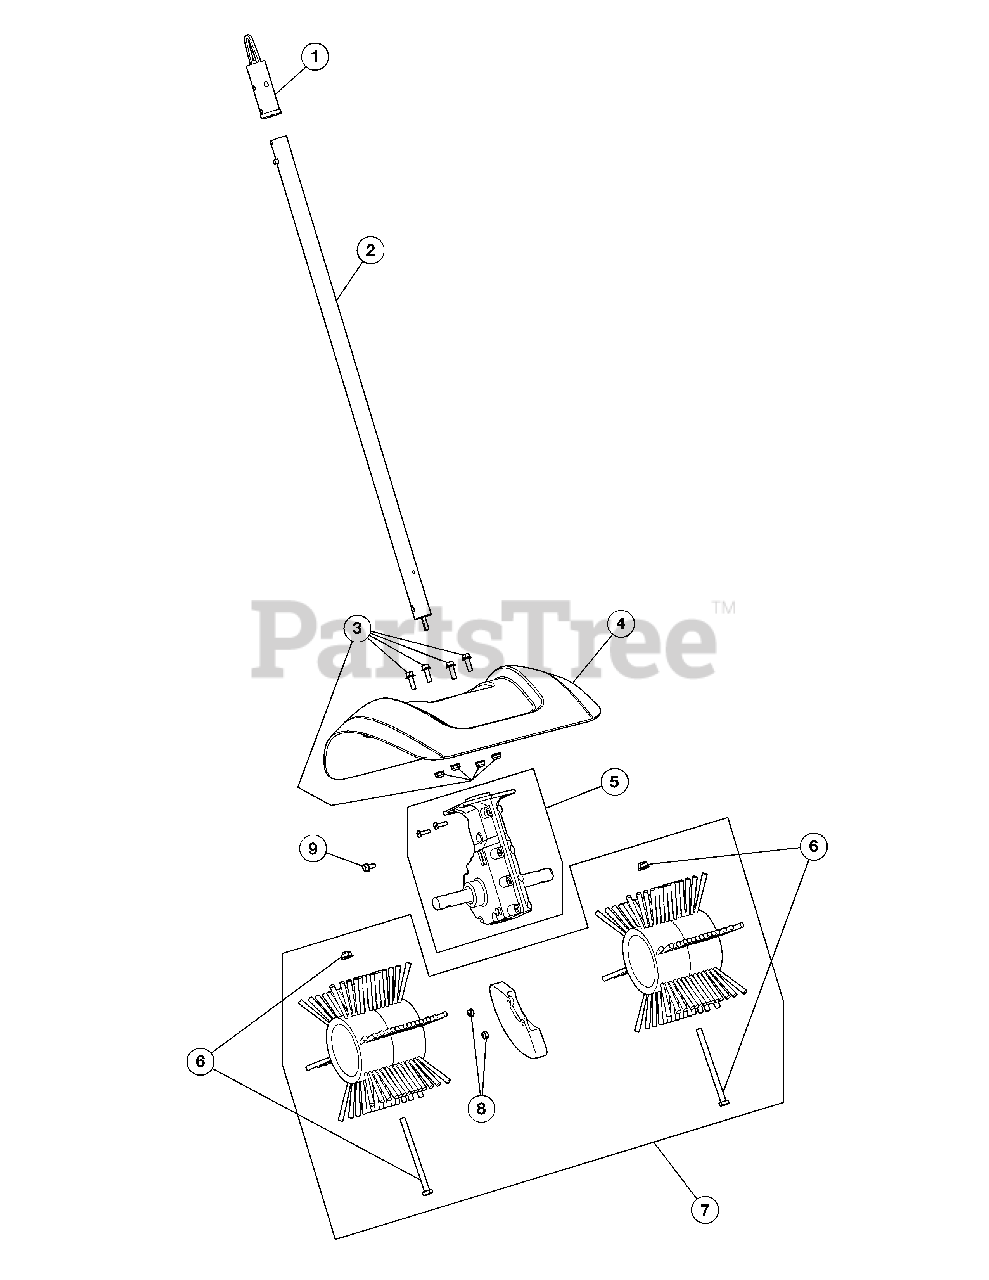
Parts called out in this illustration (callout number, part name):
1	Accessory Hanger
2	Drive Shaft Housing Assembly
3	Guard Mounting Hardware Set
4	Broom Guard
5	Gear Box Assembly
6	Brush Mounting Hardware Set
7	Brush / Skid Shoe Replacement Kit
8	Skid Shoe Mounting Nut Set
9	Bolt
